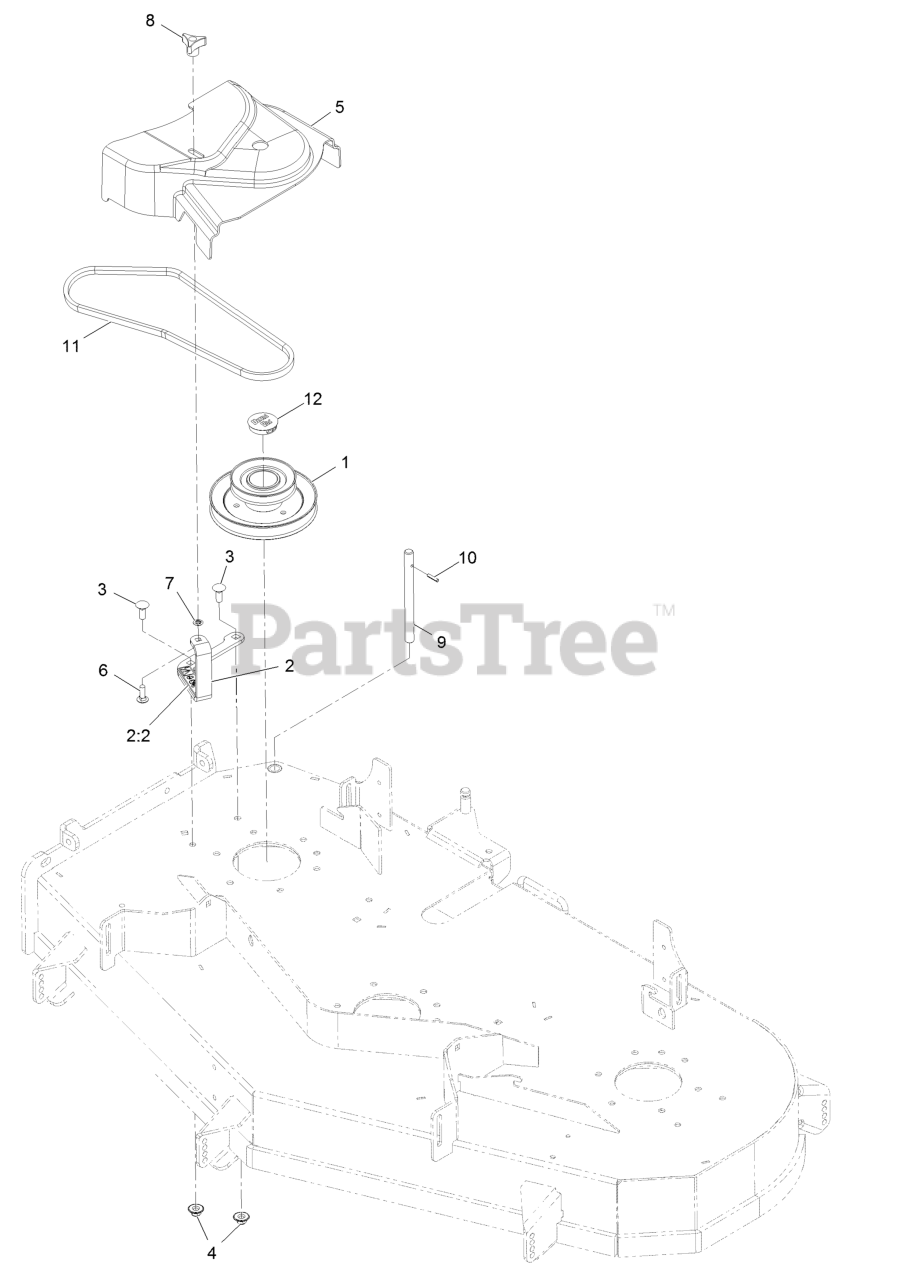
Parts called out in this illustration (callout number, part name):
1	Jackshaft,Uv Drive 524 Splined
2	ASM-Cvr Brkt W/Decal
2:2	Decal-Danger
3	Bolt-Carriage 3/8-16 X 1
4	Nut-Nyloc 3/8-16 Flg
5	Cover-Belt, Uv 52
6	Bolt-Carriage 5/16-18 X 1
7	Ring-Bolt Retaining
8	Knob-3 Prong
9	Shaft-Catcher, Grass
10	Rollpin 3/16 X 7/8
11	Belt, Blower Drive 52
